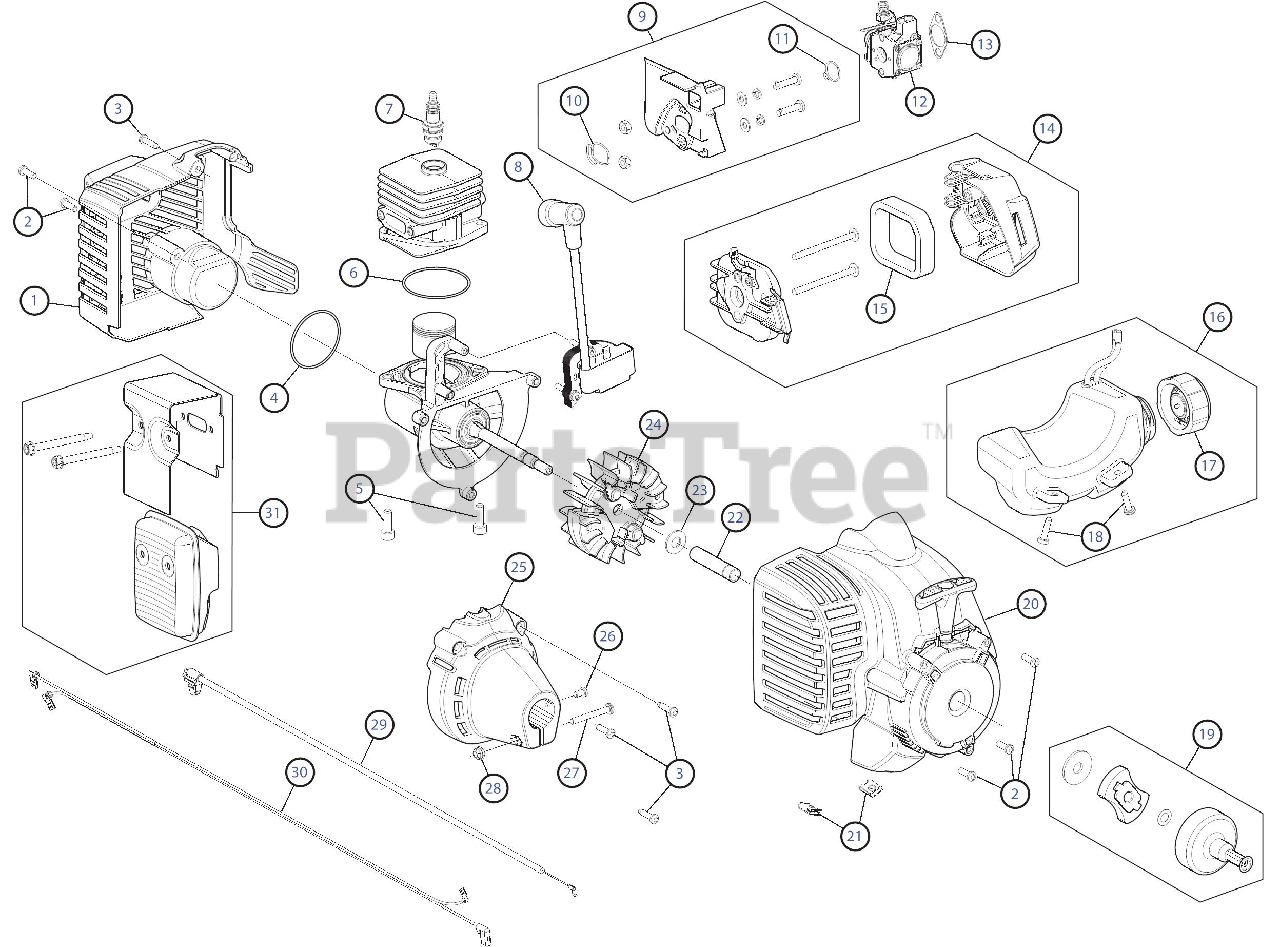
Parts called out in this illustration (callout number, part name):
1	Rear Cover Assembly (Incl. 2 & 3)
2	Housing Screw
3	Cover Screw
4	O-Ring
5	Crankcase Bolt
6	Crankcase O-Ring
7	Spark Plug
8	Module Assembly
9	Insulator Assembly (Incl. 10 & 11)
10	Insulator O-Ring
11	Carburetor O-Ring
12	Carburetor
13	Air Cleaner Gasket
14	Aircleaner Cover Assembly (Incl. 15)
15	Aircleaner Filter
16	Fuel Tank Assembly (Incl. 17 & 18)
17	Fuel Tank Cap
18	Fuel Tank Screw
19	Starter Clutch Assembly
20	Starter Housing (Incl. 2 & 21)
21	U-shaped Nut
22	Spacer
23	Washer
24	Flywheel Assembly
25	Clutch Cover (Incl. 3)
26	Anti-rotation Screw
27	Clamp Screw
28	Clamp Nut
29	Throttle Cable
30	Lead Wires
31	Muffler Assembly
